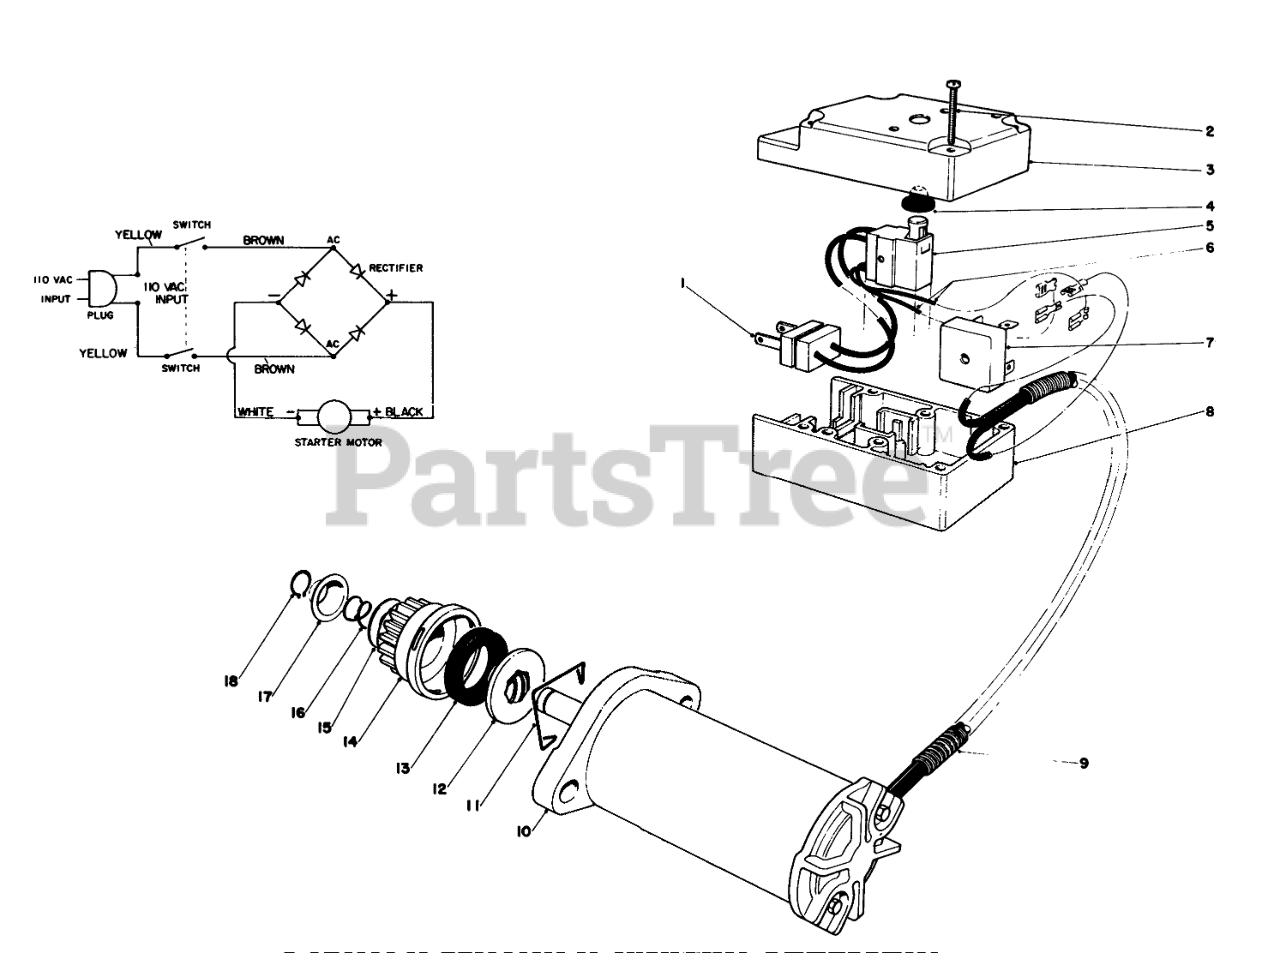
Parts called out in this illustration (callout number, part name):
1	Plug
2	SCREW-PLASTITE
3	Cap-Switch Housing
4	BOOT-SWITCH
5	SWITCH-STARTER
7	RECTIFIER-BRIDGE
8	Base-Switch Housing
9	CABLE COVER
10	Starter Motor
11	RETAINING CLIP
12	Helix Pinion Nut
13	RUBBER RING
14	Pinion
15	WASHER
16	COMP SPRING
17	PINION STOP
18	RET RING
